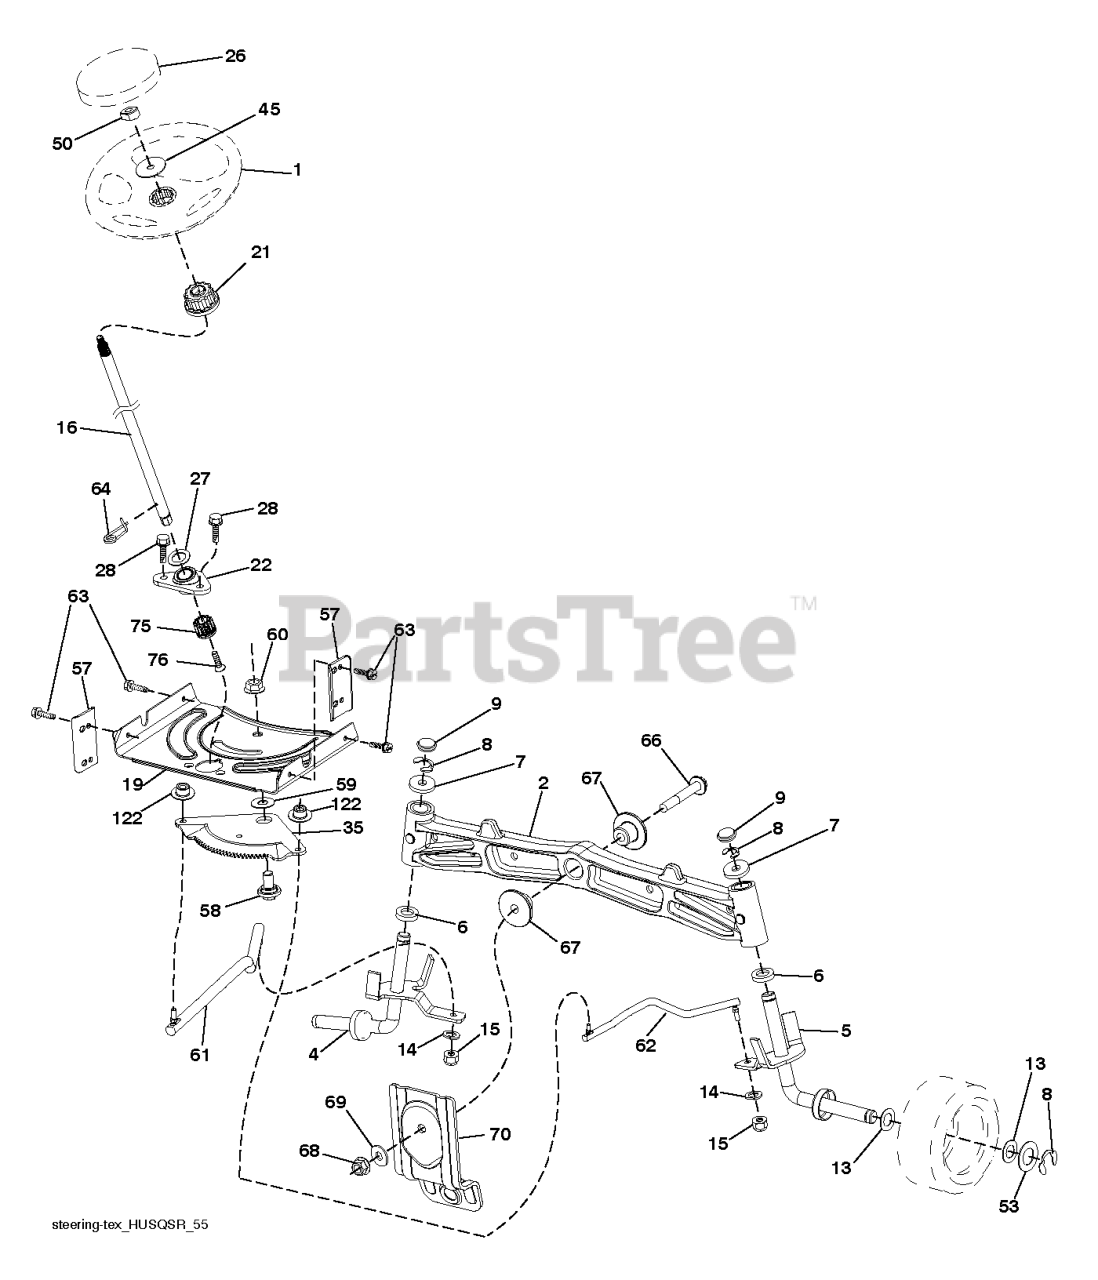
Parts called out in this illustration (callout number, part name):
1	WHEEL.STEER.HUSQ.SR.498.OVMLD
2	AXLE.CAST.IRON
4	SPINDLE.WELDED.LH.15"TEX
5	SPINDLE.WELDED.RH.15"T
6	THRUST WASHER
9	CAP.SPINDLE.BLACK
14	SLW 3/8 STD
15	NUT CROWNLOCK 3/8-24
16	KIT.SRVC.STEERINGSHAFT.2HISHFT
19	PLATE.STEER.DDL.NLT/NG
21	KIT.SRVC.STEERINGSHAFT.ADAPTER
22	KIT.SRVC.STEERINGSHAFT.LWRBSHG
26	INSERT.CAP.WHL.STRG.HUSQ.PREM
27	WASHER
27	WASHER LT
28	SCREW, 3/8-16X3/4
35	GEAR.SECTOR.PLATE.DDL.
45	WASHER 9/16"ID, 2 3/8"OD
45	WASHER.3/8ID.2-3/8OD.12GA.PLTD
50	NUT.HEX.1/2-20
50	NUT.HEX.FLANGE.3/8-16.LOCKNUT
53	WASHER.HARDENED
57	BRACKET.UPSTOP.TEX
58	BOLT.SHOULDER.SECTOR.P
59	WASHER.THURST.SECTOR.S
60	NUT FLANGE LOCK 5/8-11
61	DRAGLINK.LH.BALLSTUD.D
61	LINK.ASM.DRAG.ADJUST.LH.PLATED
62	LINK.ASM.DRAG.ADJUST.RH.PLATED
62	DRAGLINK.RH.BALLSTUD.D
63	SCREW
64	RETAINER.CLIP.SPRING.S
66	BOLT HEX FGHD 7/16-14 X 3 SERR
67	BUSHING.PM.FRONT AXLE
68	NUT.LOCK.FLANGE.7/16
69	WASHER.1.5X.505X.118
70	BRACKET.FRT.DECK.SUSP.RR.MT431
75	KIT.SRVC.STEERINGSHAFT.PINION
76	SCREW HEAD SOCKET LRVB
122	CAP.GEAR.SECTOR.TEX
